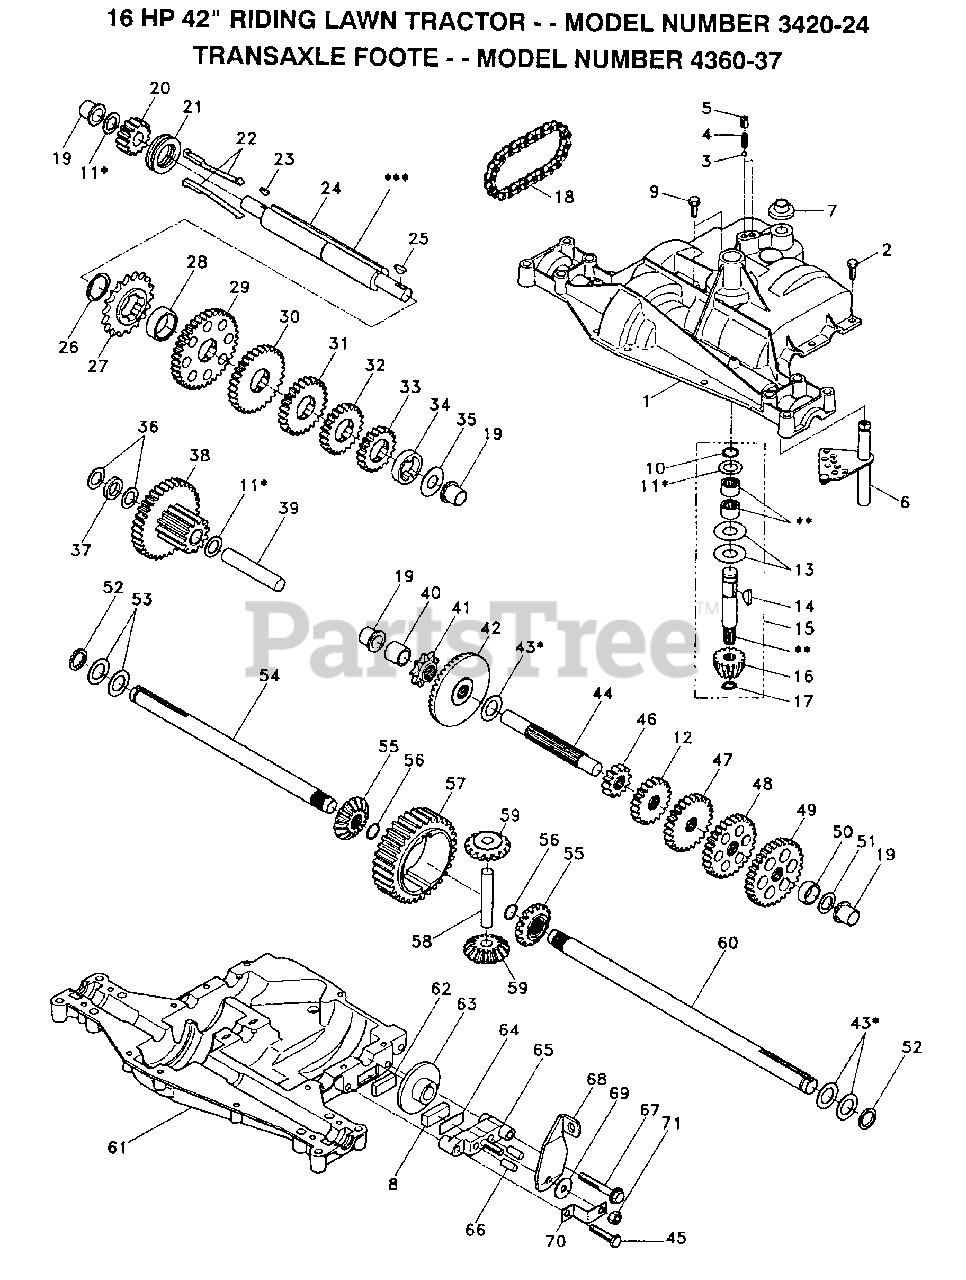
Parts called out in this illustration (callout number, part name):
1	HOUSING UPPER
3	BALL, DETENT
4	SPRING, DETENT
5	SCREW, SET
6	KIT SHIFTER ASSY
7	BOOT, SHIFTER
8	PUCK, FRICTION
9	SCREW TAPPING WITH SEALER
10	RING RETAINING
11	ASSY, KIT, SHIM .625 SHAFT
12	GEAR SPUR, 15 TEETH
13	WASHER, PLAIN .632 X 1.38 X .046
14	KEY WOODRUFF #9
15	ASSY KIT INPUT SHAFT
16	PINION BEVEL 14 TEETH
17	RING, RETAINING
18	CHAIN, 24 PITCHES
19	BEARING, FLANGE
20	GEAR SPUR, 14 TEETH
21	COLLAR CLUTCH
22	KEY CLUTCH
23	KEY WOODRUFF #3
24	SHAFT INTERMEDIATE
25	KEY, WOODRUFF, #61
26	RING, RETAINING
27	SPROCKET, 18 TEETH
29	GEAR, SPUR, 37 TEETH
30	GEAR, SPUR, 35 TEETH
31	GEAR, SPUR, 30 TEETH
32	GEAR, SPUR, 25 TEETH
33	GEAR, SPUR, 22 TEETH
34	GEAR, SPUR, 19 TEETH
35	WASHER, PLAIN .640 X 1.37 X .061
36	WASHER, PLAIN .632 X 1.00 X .026
37	SPACER .630 X 1.00 X .169
38	ASSY GEAR COMB 12&35 TEETH
39	SHAFT, IDLER
40	SPACER .635 X .875 X .755
41	SPROCKET, 9 TEETH
42	GEAR, BEVEL, 42 TEETH
43	ASSY, KIT, SHIM .750 SHAFT
44	SHAFT, DRIVE
45	SCREW TAPPING
46	GEAR, SPUR, 12 TEETH
47	GEAR, SPUR, 20 TEETH
48	GEAR, SPUR, 25 TEETH
49	GEAR, SPUR, 28 TEETH
50	GEAR, SPUR, 31 TEETH
51	WASHER, PLAIN .632 X 1.00 X .060
52	WASHER, NEOPRENE
53	WASHER, PLAIN .758 X 1.25 X .031
54	AXLE LEFT HAND
55	GEAR MITER 15 TEETH
56	RING, RETAINING
57	GEAR, SPUR, 32 TEETH
58	SHAFT, CROSS
59	GEAR, MITER, 15 TEETH
60	AXLE, R.H.
61	HOUSING LOWER
62	PUCK, FRICTION
63	DISC, BRAKE
65	JAW, BRAKE
66	PIN, DOWEL
67	SCREW, SELF-TAPPING
68	LEVER, ACTUATING
69	WASHER, PLAIN .321 X 1.00 X .055
70	BRACKET, ANTI-ROTATION
71	LOCKNUT 5/16-24
